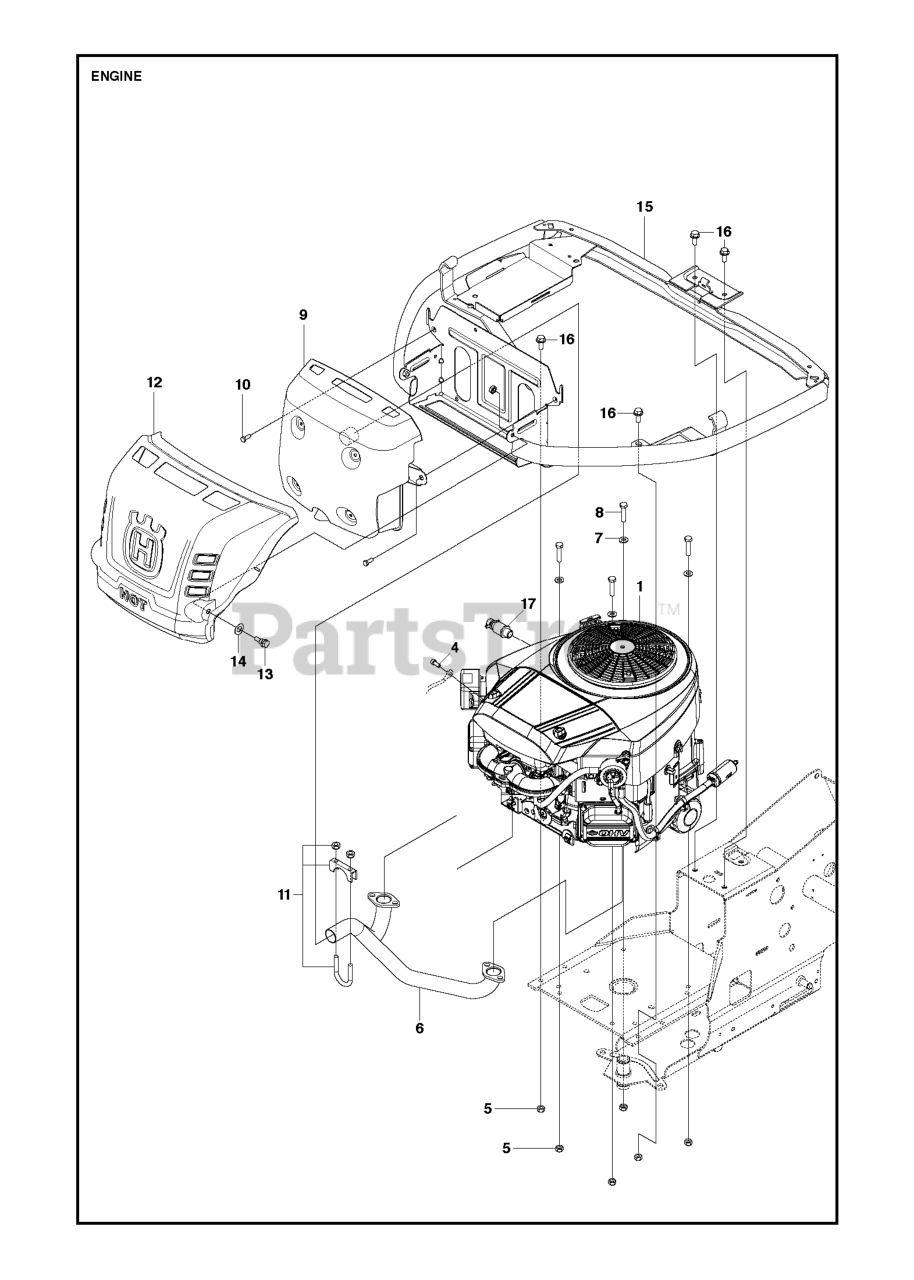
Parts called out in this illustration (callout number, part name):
5	LOCKNUT M8
7	WASHER BRB 8.4X17
11	CLAMP ASSY EXHAUST
12	HEAT SHIELD
14	SPRINGWASHER
17	VALUE.OIL.DRAIN
